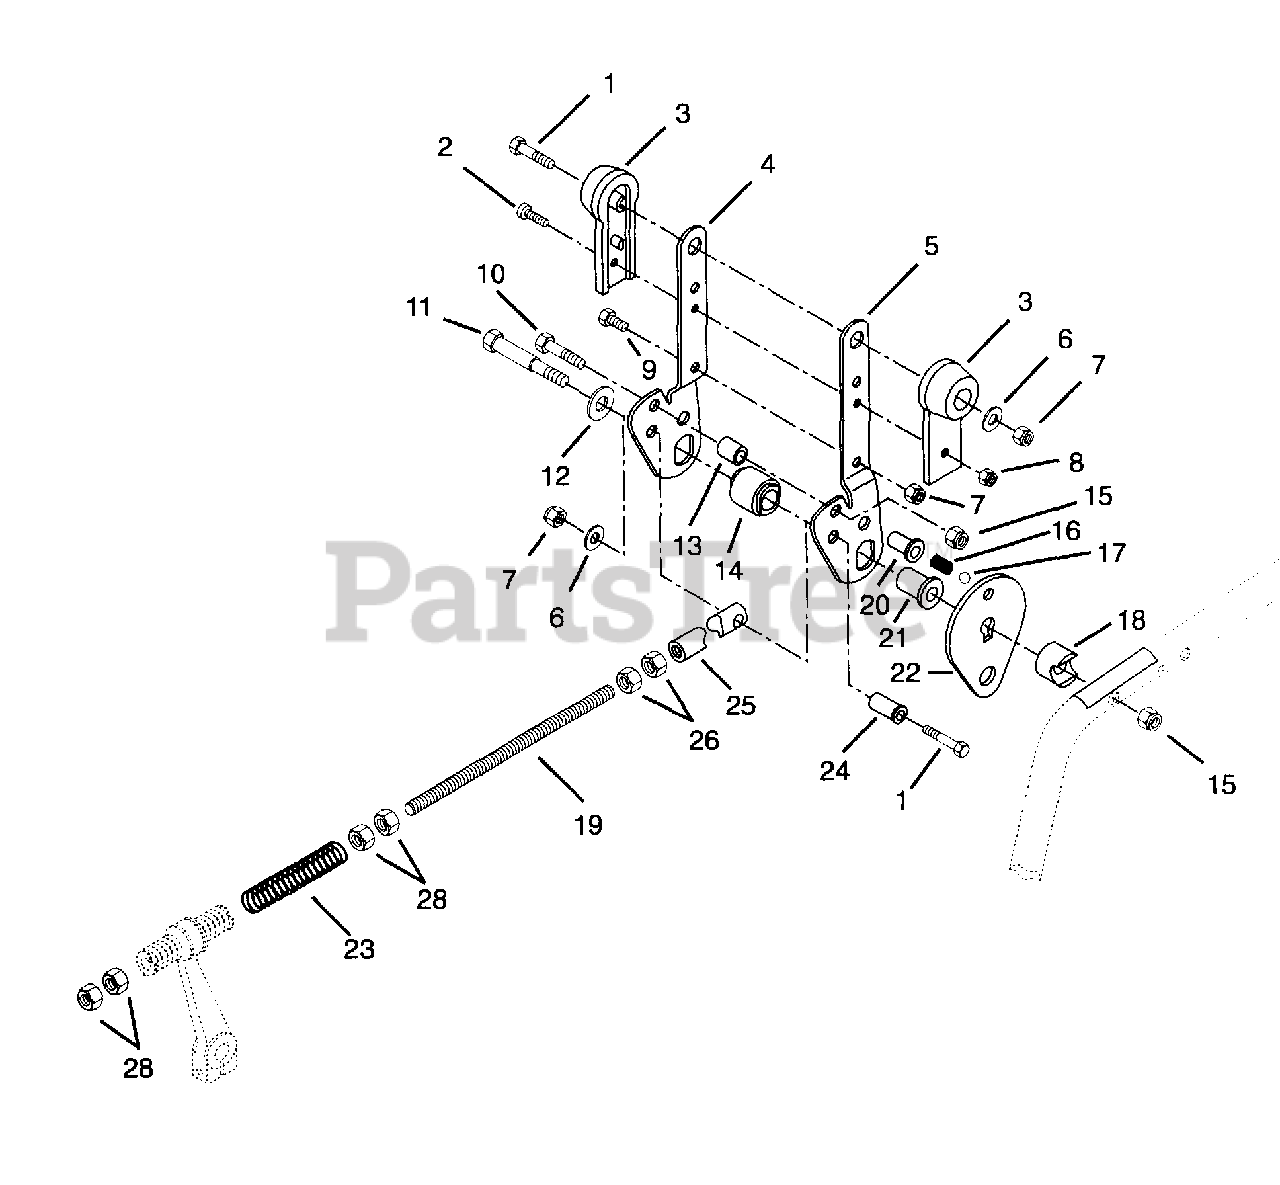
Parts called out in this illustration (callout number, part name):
1	Bolt-Hex .25-20 x 1.50 Grade 5
2	Screw-Machine 6-32 x .75
3	Knob, Handle Control
4	Handle, Control Right Hand
5	Handle, Control Left Hand
6	Washer-Flat-Steel .281 x .620 x .065
7	Nut-Locking-Center .250-20 Grade 2
8	Nut-Locking-Nylon 6-32
9	Bolt-Hex .25-20 x .63
10	Bolt-Hex .38-16 x 1.50 Grade 5
11	Bolt-Hex .38-16 x 3.5
12	Washer-Flat-Steel .531 x 1.062 x .095
13	Sleeve, Handle Stop
14	Bushing Flange .751 x 1.13 x 1.07
15	Nut-Locking-Center .375-16 Grade 2
16	Spring-Compression .038 x .281 x .88
17	Ball, .312 Guard 2000
18	Bracket, Handle Pivot
19	Nut-Jam .375-16
20	Bushing-Flange .320 x .750 x 1.280
21	Bushing-Flange .515 x .746 x 1.290 x 1.000
22	Plate, Neutral
23	Spring-Compression .072 x .561 x 2.50
24	Bushing-Flange .257 x .38 x 1.080
25	Rod, Control Forward Reverse
26	Nut-Hex .375-16 Grade 2
27	Rod, Extension
